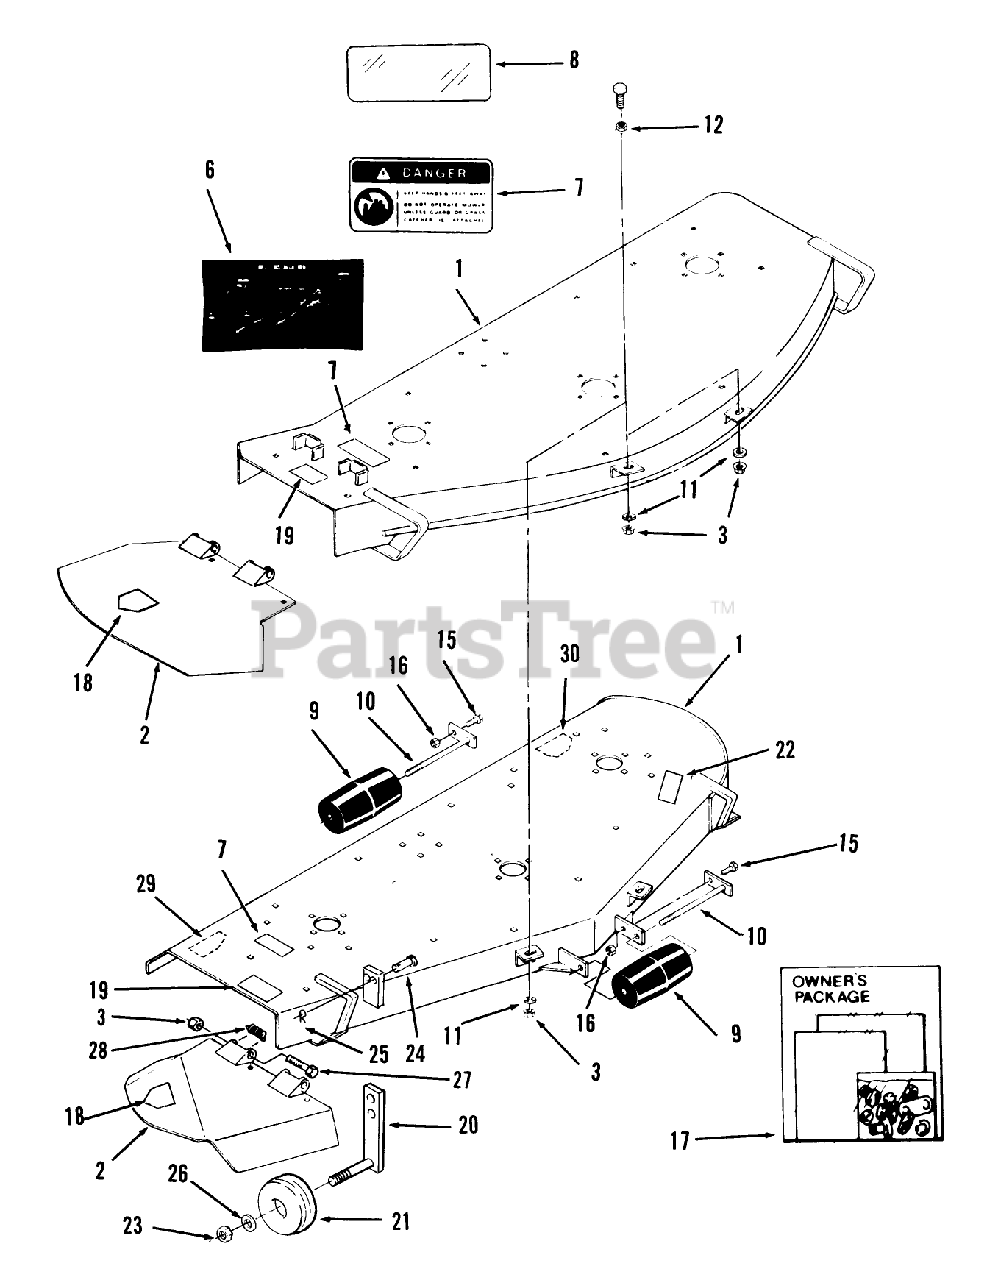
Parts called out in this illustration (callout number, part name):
1	Mower Deck-50" Mower
2	Discharge Chute-50" Mower
3	NUT-LOCK, NI
6	DECAL-BELT INSTAL
7	DECAL-DANGER, THROWN OBJECT
8	DECAL-OVERLAY
9	ROLLER-ANTI SCALP
10	ROLLER-SHAFT
11	WASHER-FLAT
12	NUT-FLANGE
15	BOLT-CARR
16	NUT-LOCK, NI
17	Loose Parts Package-60" Mower
18	DECAL-DANGER
19	DECAL-DANGER
20	GAGE-WHEEL
21	WHEEL-GAGE
22	DECAL - WHEEL ADJUSTMENT
23	NUT
24	Pin-Clevis
25	Hairpin
26	WASHER-FLAT
27	SCREW-HH
28	SPRING
29	Wear Plate RH
30	Plate-Wear, L.H.
